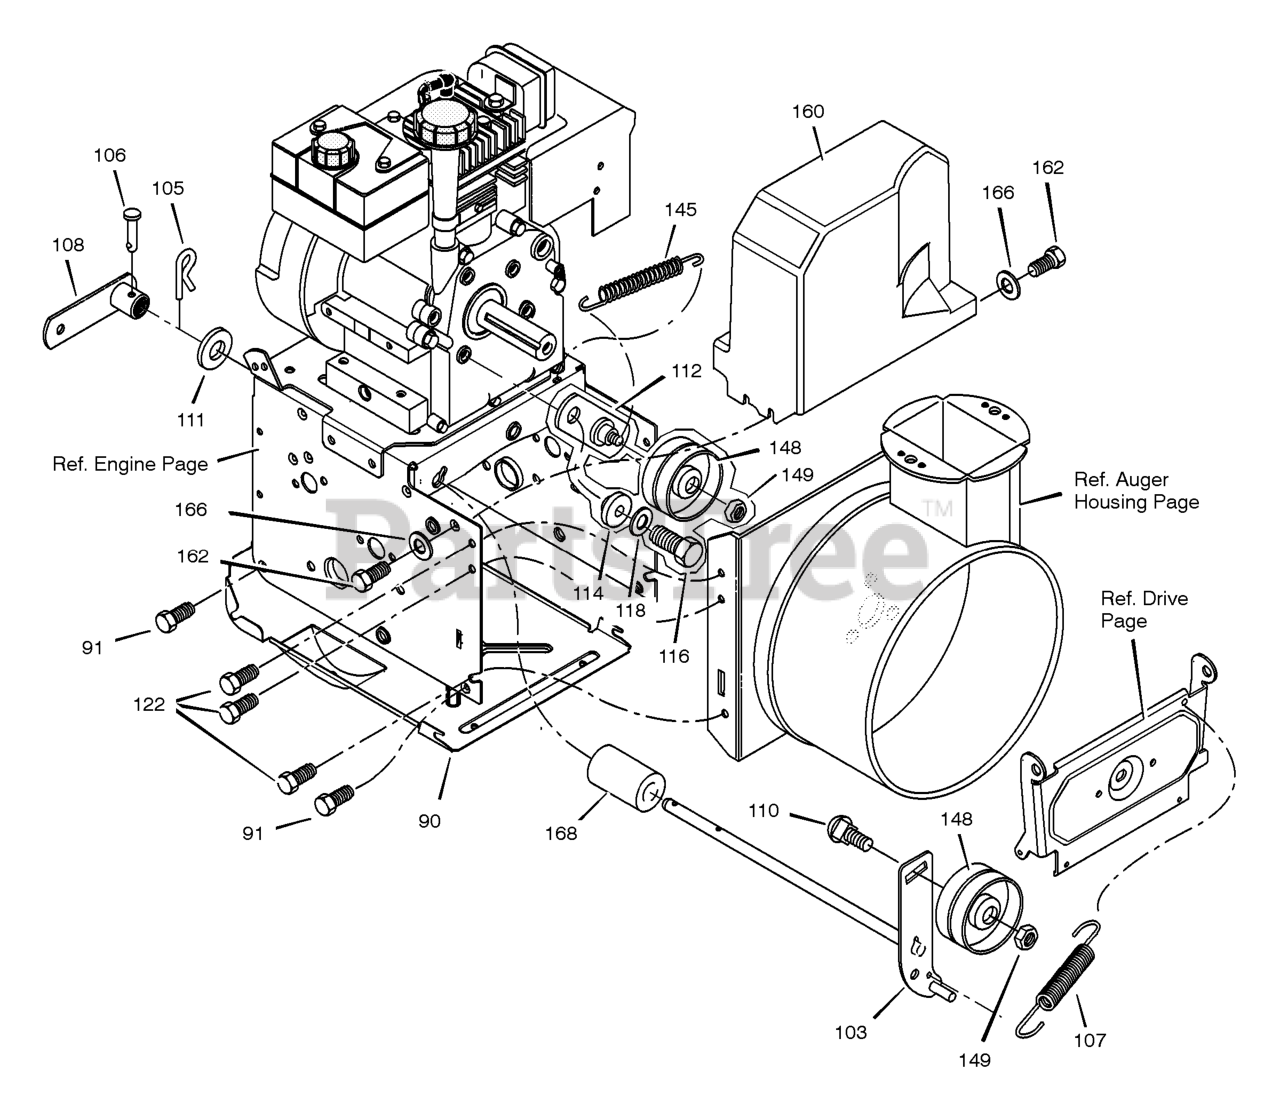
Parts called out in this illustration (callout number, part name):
88	SCREW, 5/16-18 x 0.50
90	COVER, BOTTOM
91	SCREW, 1/4-20X .63
103	IDLER ASSEMBLY, AUGER
105	PIN, HAIR .38DIAX1.64LG
106	PIN, CLEVIS 3/16" DIA
107	SPRING, TENSION
108	ASSY., SPRING ATTACH
110	BOLT, 3/8-16X1.25 CARR.
111	WASHER, FLAT
112	BRACKET ASSEMBLY, IDLER
114	BUSHING, IDLER BRACKET
116	SCREW 5/16-24 X .75
118	WASHER, SPLIT
122	SCREW, TAP 5/16-18 X .50
145	SPRING, IDLER TRACTION DRIVE
148	PULLEY, IDLER
149	NUT, JAM 3/8-16
160	COVER, BELT
162	SCREW, Hex Head
166	WASHER, FLAT
168	SPACER, AUGER BRACKET
